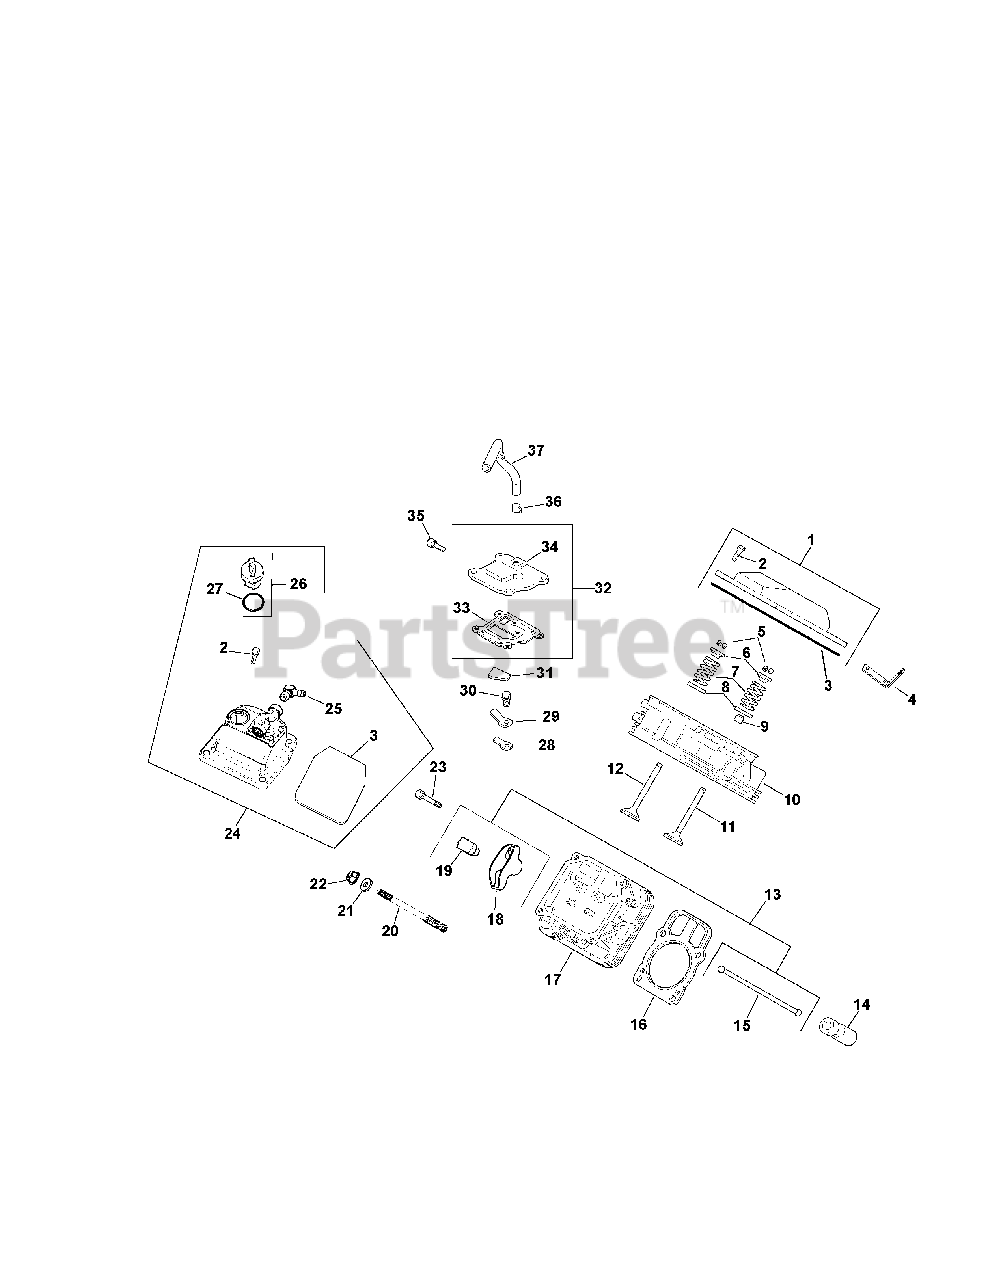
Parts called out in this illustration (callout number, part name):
1	Kit, valve cover - plain (Includes 2,3)
2	Screw, hex. flange M6x1.0x30 (4)
3	O-Ring, valve cover
4	Strap, lifting
5	Kit, retainer (4)
6	Cap, valve spring (4)
7	Spring, valve (4)
8	Retainer, spring (4)
9	Seal, valve stem (2)
10	Head assembly, #1 cylinder
11	Valve, intake (Std.) (2)
12	Valve, exhaust (Std.) (2)
13	Kit, valve train (Includes 15,18,19)
14	Lifter, valve (4)
15	Rod, push (4)
16	Kit, cylinder head gasket (Includes 21,22) (2)
17	Head assembly, #2 cylinder
18	Arm, rocker (4)
19	Pivot, rocker arm (4)
20	Stud, cylinder head (8)
21	Washer, plain (8)
23	Screw, hex flange M6x1.0x34 (4)
24	Kit, fuel pump valve (Includes 2,3,25-27)
25	Fitting, 90° (2)
26	Cap assembly, oil fill (Includes 27)
27	O-Ring
28	Reed, breather
29	Retainer, breather reed
30	Screw, hex. flange M5x0.8x10
31	Filter, breather
32	Kit, breather (Includes 33,34)
33	Gasket, breather
34	Cover, breather
35	Screw, hex. flange M6x1.0x20 (4)
36	Clamp, breather
37	Hose, breather
